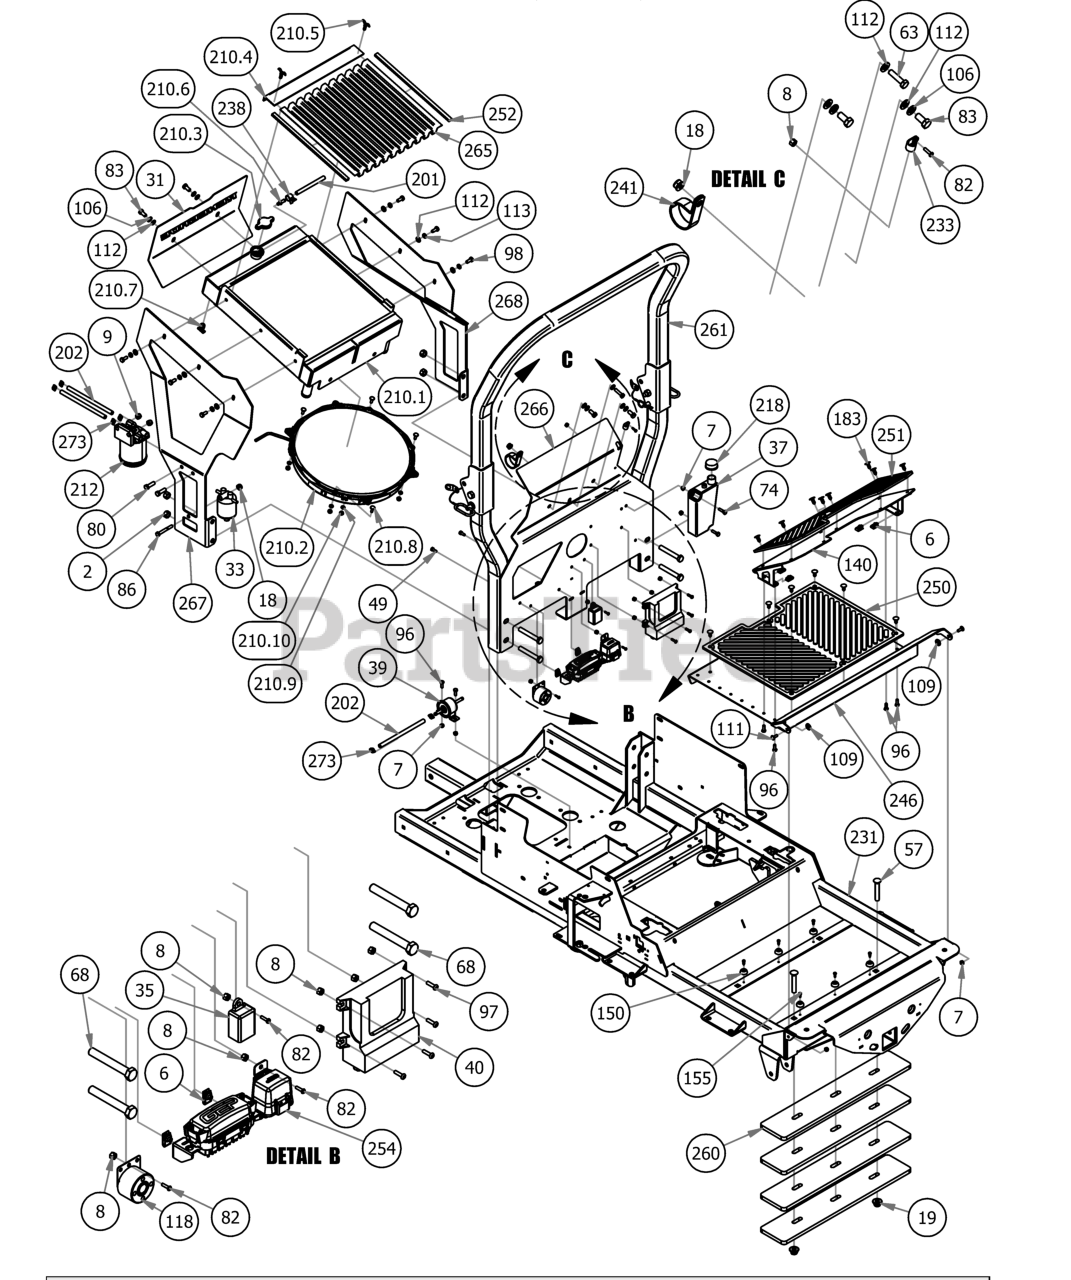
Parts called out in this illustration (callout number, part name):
2	1/2" Center Lock Nut
6	1/4-20 Cage Nut
7	1/4-20 Hex flang lock nut
8	10-24 Nylon Insert Locknut
9	3/8 Nylock Nut
18	5/16-18 Nylon Flange Nut
19	1/2-13 NYLON INSERT FLANGE LOCKNUT ZINC
31	2019 Diesel Upper Rear Cover
33	Caterpillar Fuel Bowl Kit
35	Auto Shut Down for Cat Diesels
37	overflow Reservoir- 27Kaw & 28/35Hp Diesel
39	Electric Fuel Pump
40	ECM for 1100cc Diesel
49	M6-1.0 X 16MM Hex Bolt
57	1/2-13 x 3 Carriage Bolt Grade 5
63	5/16 x 1 1/4 Hex Bolt
68	1/2 x 3 1/2 Flange Bolt Grade 8
74	1/4-20 x 1 GR 5 hex bolt zinc
80	3/8" x 1 1/4" Hex Bolt
82	10-24 X 5/8 BS Button Head Bolt
83	3/8" x 3/4" Hex Bolt
86	5/16" x 2 1/2" Bolt
96	1/4" x 3/4" Hex Bolt
97	10-24 x 1 BS C/S 18-8 SS
98	5/16" x 3/4" Hex Bolt
106	3/8" Lock Washer
109	.360 ID Plastic Washer
111	1/4" x 3/4" Carriage Bolt
112	5/16" Flat Washer
113	5/16" Lock Washer
118	Heat Warning Piezo Buzzer
140	2019 Outlaw Adjustable Foot Plate
150	Button Bumper
155	#10 x 1/2" Self Tapping Screw
183	Ratchet Fastener
201	5/16 Clear Hose x 42"
202	5/16 Fuel Line Hose - Priced Per Foot
210	2019 Diesel Radiator Kit
210.1	2019 Diesel Radiator
210.2	Electric Fan for 2019 Diesel Radiator
210.3	radiator cap
210.4	Screen Rentention Plate for 2019 Diesel Radiator
210.5	1/4-20 x 3/4 Thumb Screw
210.6	1/4 Barb to 3/16 NPT Overflow Fitting
210.7	1/4 NPT Drain Plug
210.8	1/4" x 3/4" Carriage Bolt
210.9	1/4" Lock Washer
210.10	1/4-20 Hex Nut
212	Fuel Filter
218	Reservoir Tank Cap-Overflow
231	2019 Horizontal Diesel Frame
233	3/8 Cable Clamp-Black Nylon
238	5/8 Hose Clamp
241	Diesel Clamp 1 3/4" Vinyl
246	2019 Outlaw Floorboard
250	OUTLAW2019_FLOORMAT
251	FLOORMAT_OUTLAW_2019
252	Rubber Trim
254	2019 24.7 Diesel Harness
260	2019 Outlaw Counter Weight
261	2019 2X2 Folding ROPS
265	Radiator Screen - Diesel
266	2019 Diesel Radiator Mount - Front
267	2019 Diesel Radiator Mount - Right
268	2019 Diesel Radiator Mount - Left
273	2 EAR CLAMP 12.5mm-15mm
